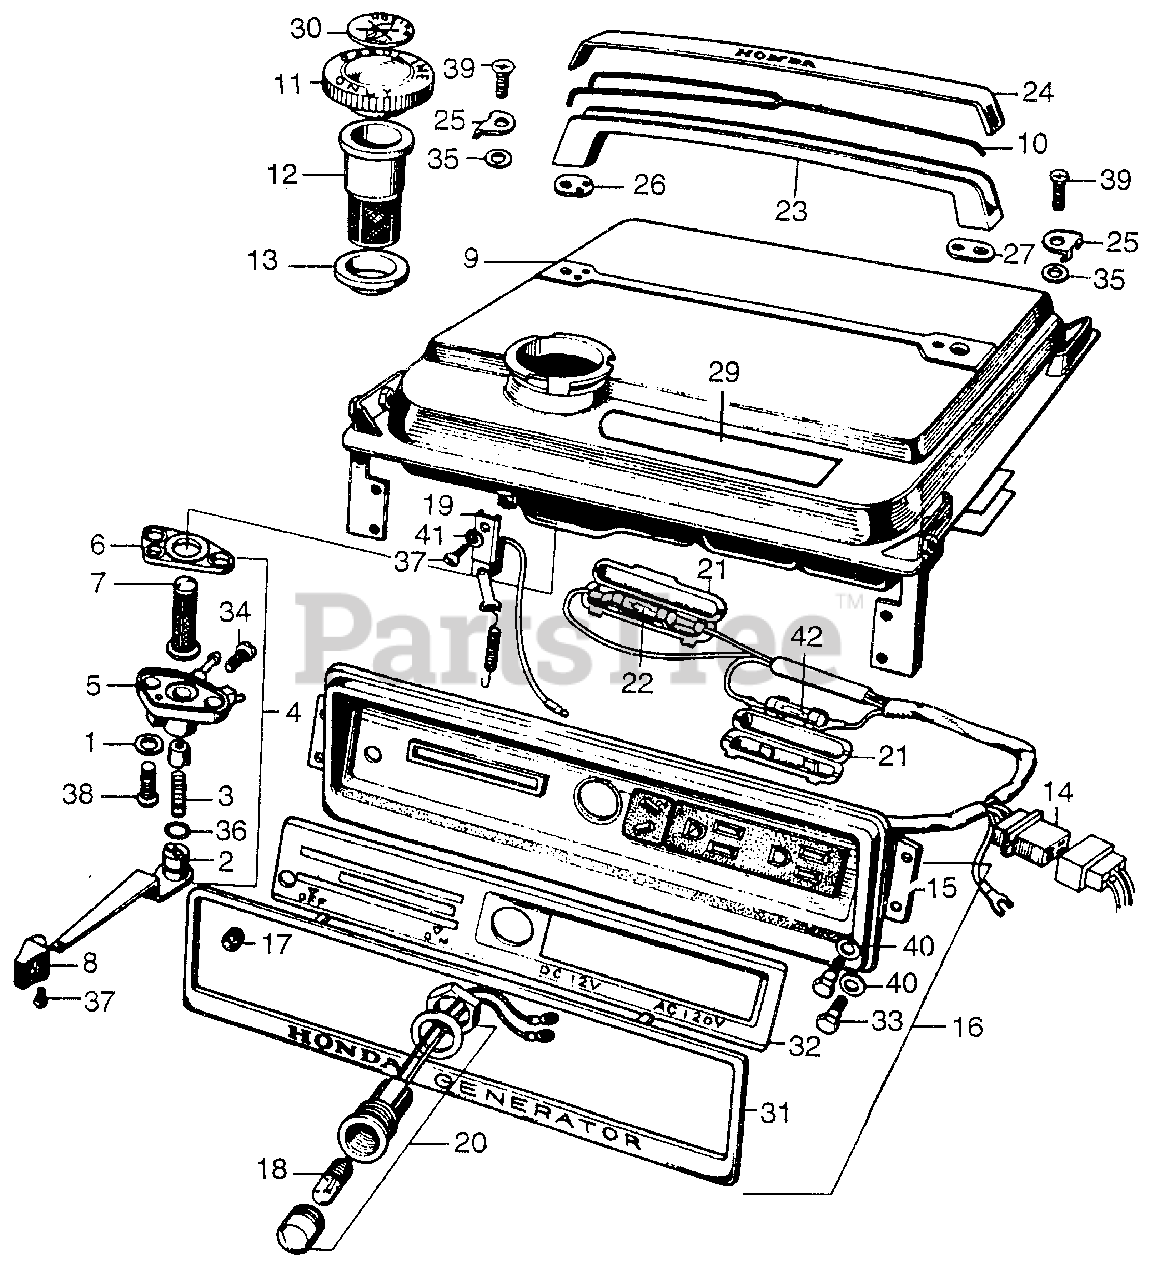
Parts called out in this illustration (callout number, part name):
1	GASKET, STRAINER SETTING (NOT AVAILABLE)
2	LEVER, VALVE (NA USE ALT:16950-836-703)
3	SPRING, VALVE (NOT AVAILABLE)
4	PETCOCK ASSY. (NOT AVAILABLE)
5	BODY, PETCOCK (NA USE ALT:16950-836-703)
6	GASKET A, PETCOCK (NOT AVAILABLE)
7	FILTER, CHECK (NOT AVAILABLE)
8	KNOB, ON-OFF (NOT AVAILABLE)
9	TANK, FUEL *PB1* (DARK BLUE) (NOT AVAILABLE)
10	TUBE, HANDLE BREATHER (NOT AVAILABLE)
11	CAP, TANK
12	FILTER, OIL
13	RUBBER, FILTER (NOT AVAILABLE)
14	CONNECTOR (4P)
15	PANEL, FR. (ONLY AVAILABLE AS ASSEMBLY) (NOT AVAILABLE)
16	PANEL, FR. (NOT AVAILABLE)
17	GROMMET, CONTROL
18	BULB (24V2W)
19	SWITCH ASSY., ENGINE (NOT AVAILABLE)
20	SOCKET ASSY., PILOT LAMP (NOT AVAILABLE)
21	HOLDER, FUSE
22	FUSE (3A)
22	FUSE ASSY., SPARE
23	HANDLE, CARRY
24	COVER, HANDLE (NOT AVAILABLE)
25	HOOK, HANDLE COVER
26	GASKET A, HANDLE
27	GASKET B, HANDLE
29	MARK A, CAUTION (NOT AVAILABLE)
30	MARK, TANK CAP CAUTION
31	MOLDING, FR. PANEL
32	PLATE, FR. PANEL
33	BOLT, FAN COVER (NOT AVAILABLE)
34	SCREW, STOP
35	O-RING (5X1.5) (NOT AVAILABLE)
36	O-RING (9X1.3) (NOT AVAILABLE)
37	SCREW, PAN (3X6) (NOT AVAILABLE)
38	SCREW, PAN (6X16)
39	SCREW, PAN (6X20)
40	WASHER, PLAIN (5MM)
41	WASHER, SPRING (3MM)
42	FUSE A (10A)
